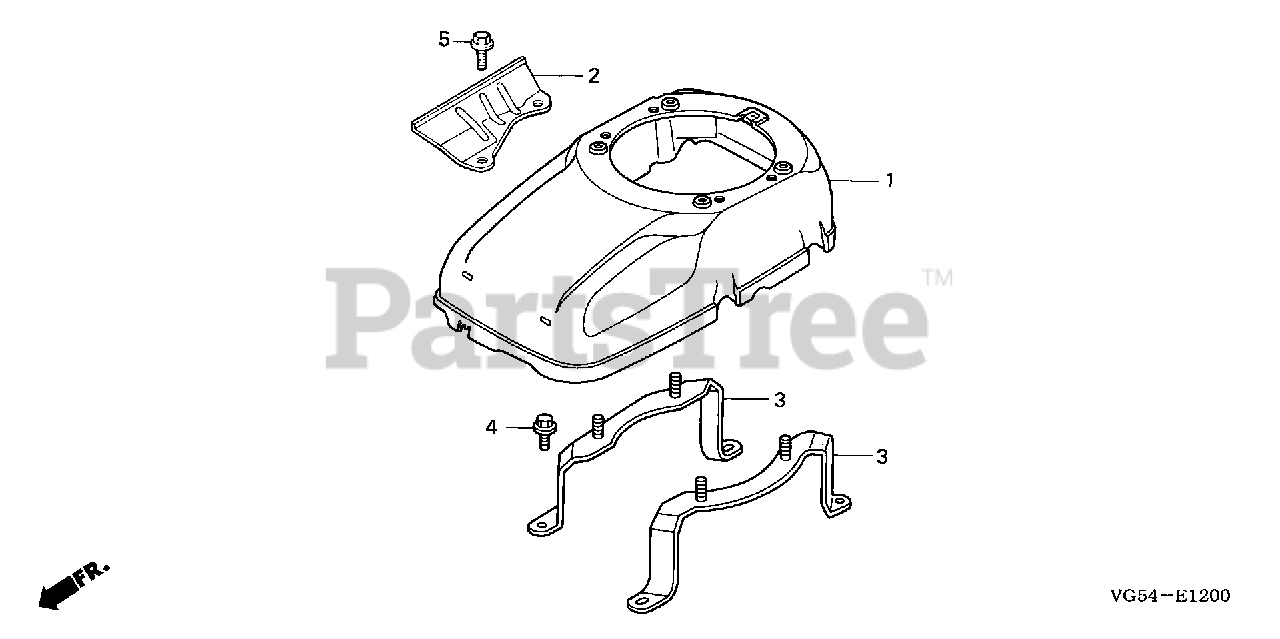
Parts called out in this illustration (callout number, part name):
1	COVER, FAN *R8* (BRIGHT RED)
2	PLATE, SIDE
3	BRACKET, FAN COVER
4	BOLT, FLANGE (6X16)
5	BOLT, FLANGE (8X20)
